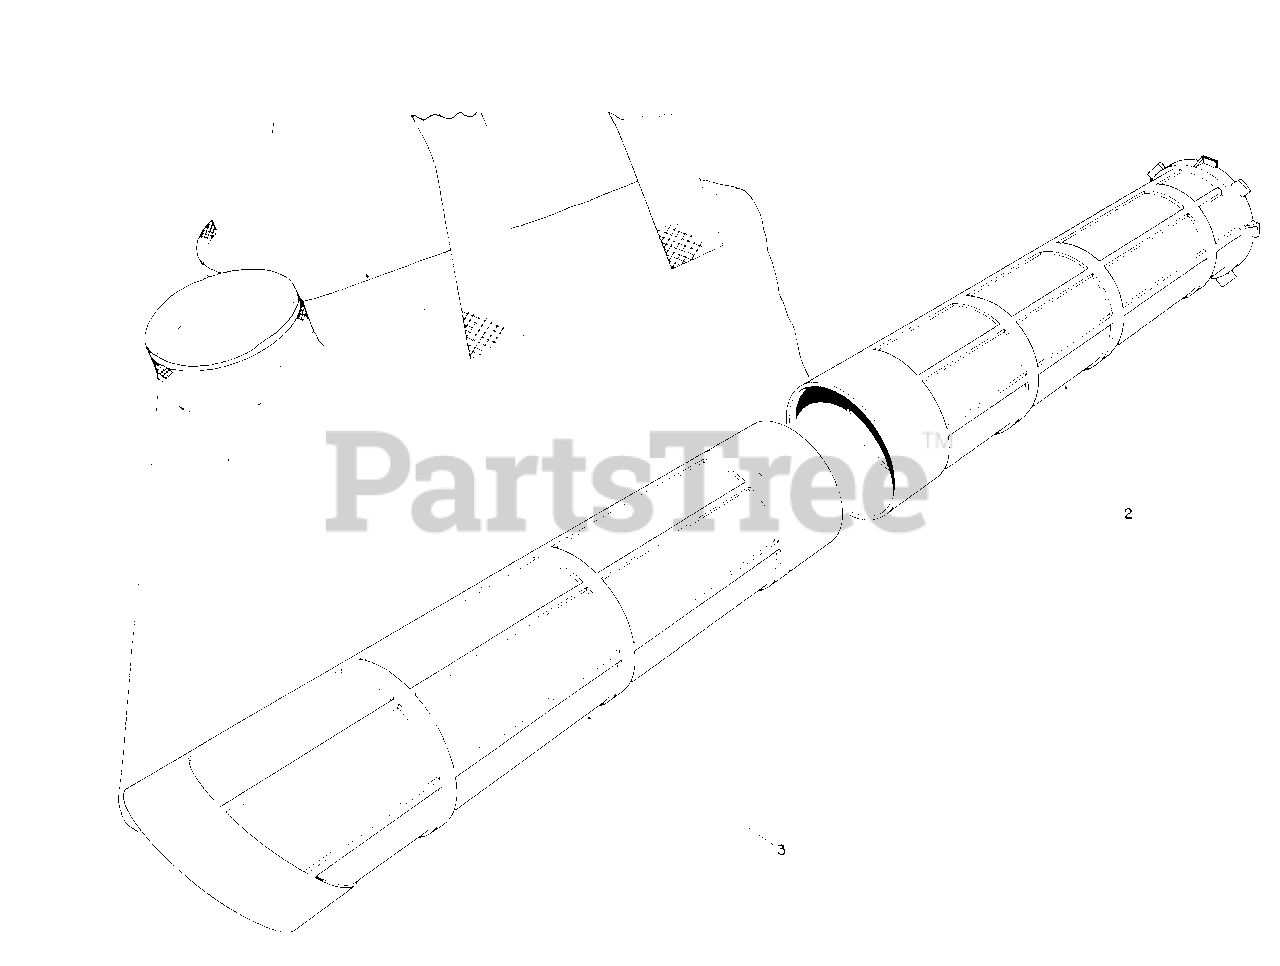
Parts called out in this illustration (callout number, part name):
1	Bag-Vacuum
2	Tube-Upper Vacuum
3	tube-Lower Vacuum
